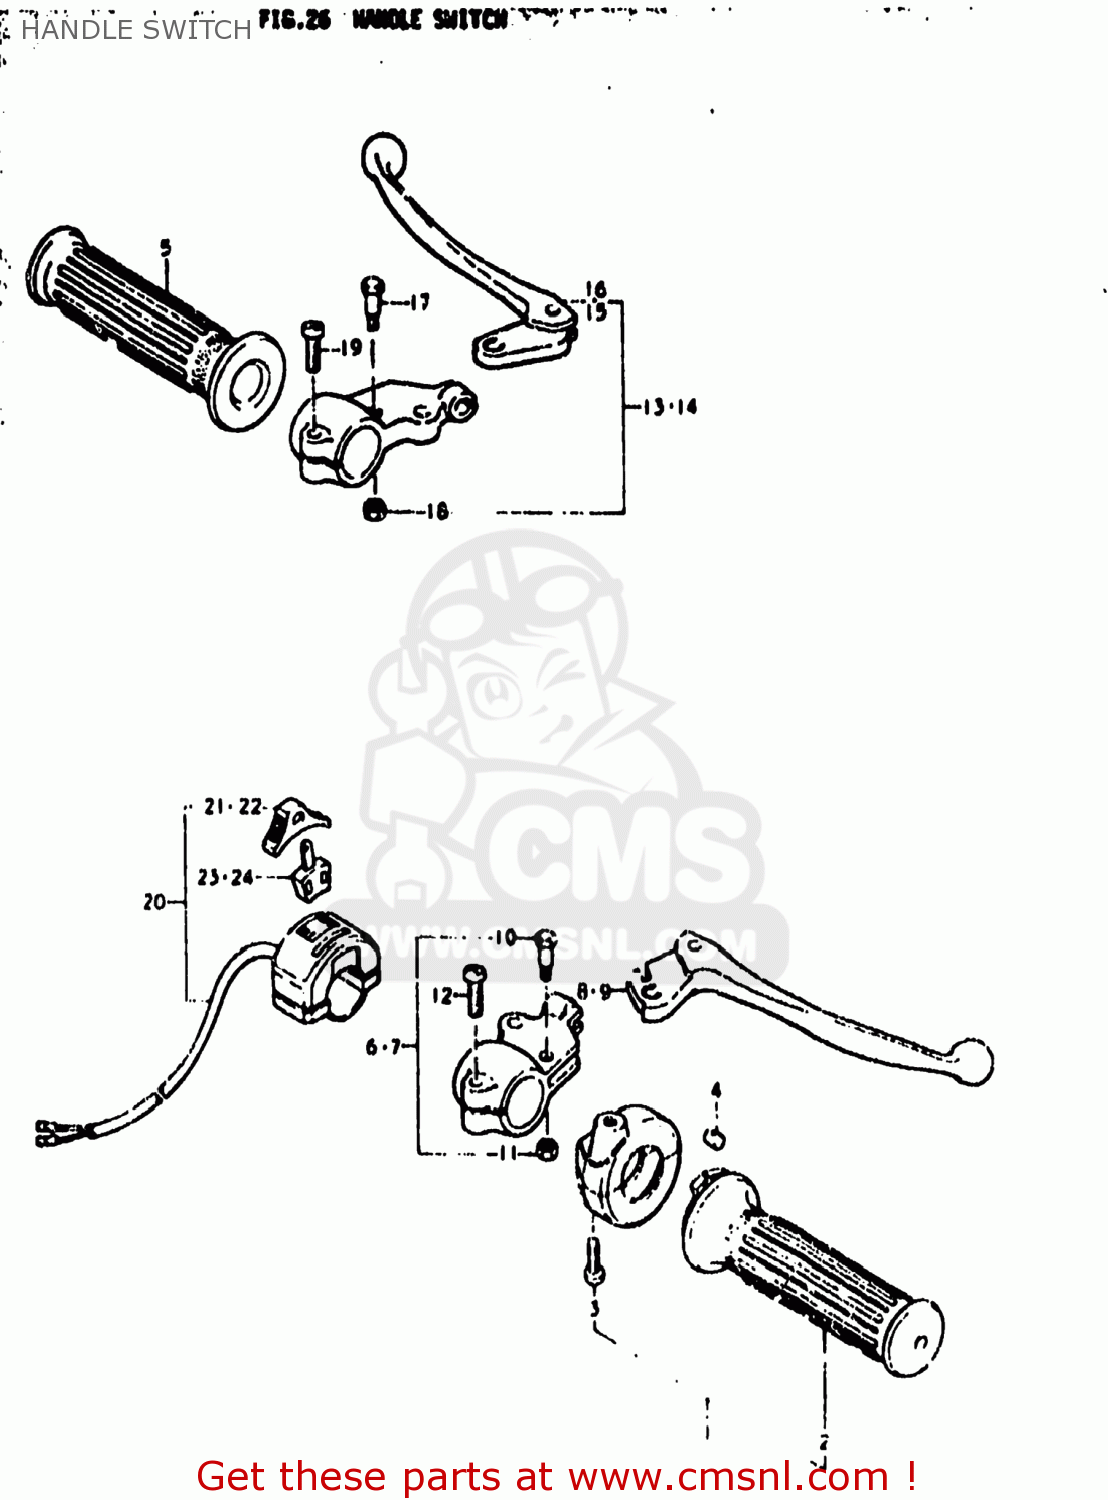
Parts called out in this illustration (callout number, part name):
1	CASE ASSEMBLY,THROTTLE
2	GRIP,THROTTLE
3	SCREW
4	PIECE,THROTTLE END
5	GRIP,LEFT
6	LEVER ASSEMBLY,BRAKE
7	LEVER ASSEMBLY,BRAKE
8	LEVER,BRAKE
9	LEVER,BRAKE
10	BOLT,LEVER
11	NUT
12	SCREW
13	LEVER ASSEMBLY
14	LEVER ASSEMBLY
15	LEVER,CLUTCH
16	LEVER,CLUTCH
17	BOLT,LEVER
18	NUT
19	SCREW
20	SWITCH ASSEMBLY,LIGHTING
21	KNOB, LIGHTING C
22	KNOB,LIGHTING & DIMMER
23	BLOCK,LIGHTING/DIMMER
24	BLOCK,LIGHTING/DIMMER
